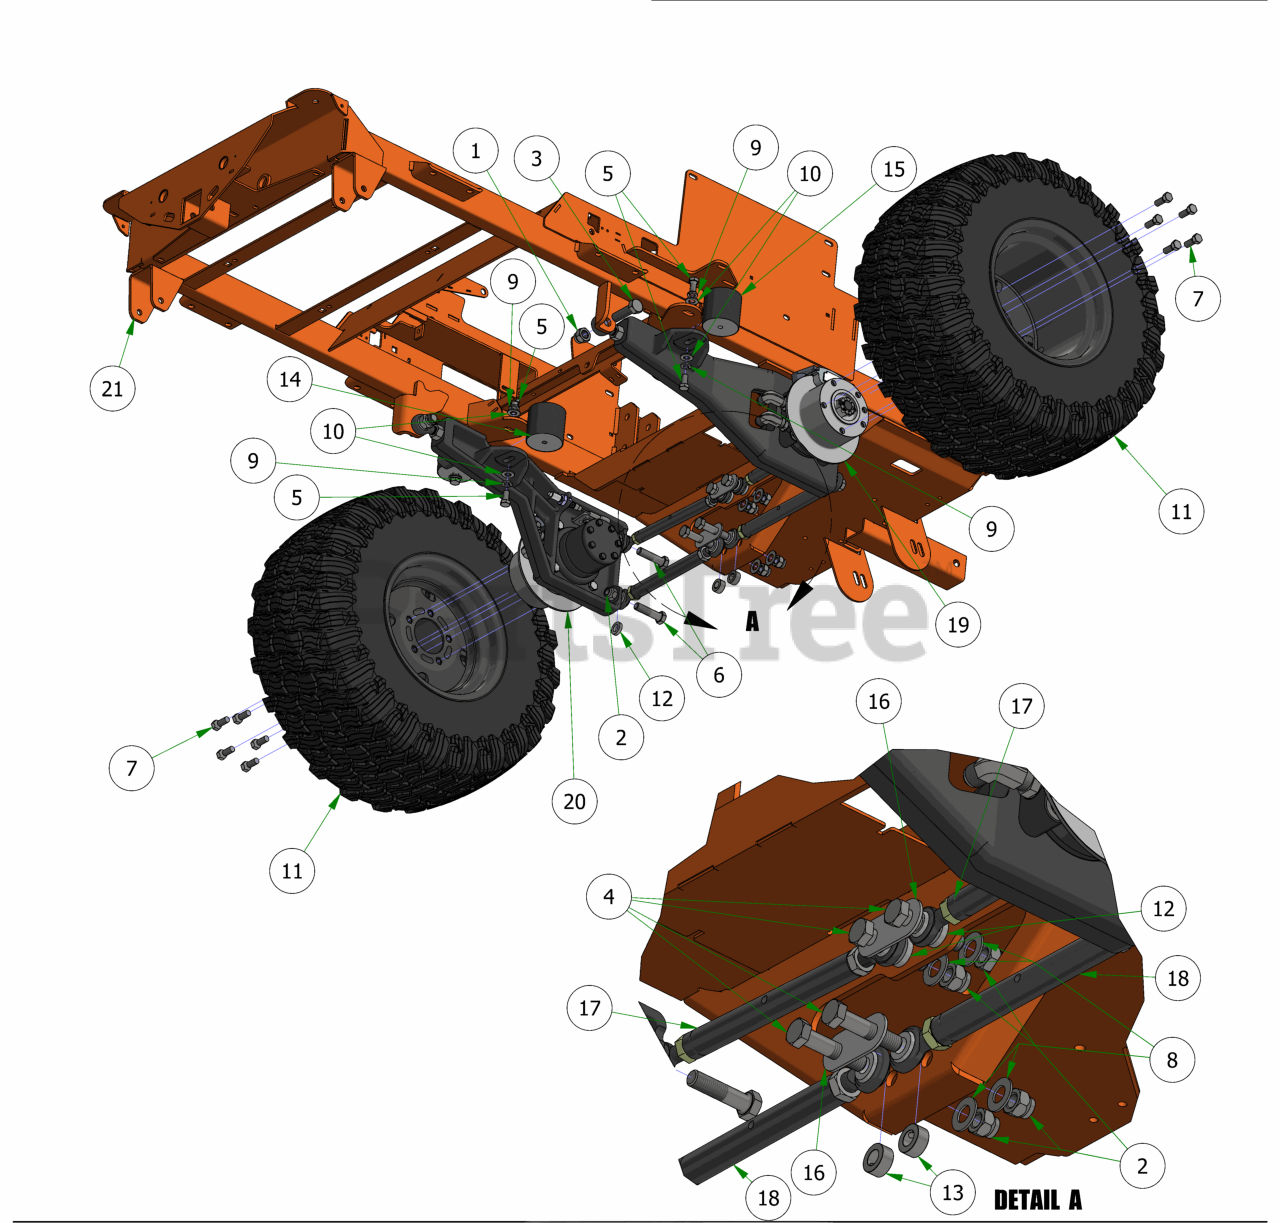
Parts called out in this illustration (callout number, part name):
1	3/4-10 NYLON INSERT LOCKNUT ZINC
2	5/8-11 NYLON INSERT LOCKNUT ZINC
3	3/4-10 X 2-1/2 HEX CAP SCREW (GR.5) ZINC
4	5/8-11 X 2-3/4 HEX CAP SCREW (GR.5) ZINC
5	1/2-13 X 1 HEX CAP SCREW (GR.5) ZINC
6	5/8-11 X 2-1/2 HEX CAP SCREW (GR.5) ZINC
7	1/2-20 x 60° Lug Bolts Zinc Grade 8
8	5/8" Flat Washer SAE Spec Grade 8
9	1/2 SPLIT LOCKWASHER (GR.8) ZINC/YELLOW
10	1/2 SAE FLAT WASHER (1-1/16" OD) GR.8 ZINC YELLOW
11	2019 Assy-26x12-12 Reaper Turf -10.5" Rim
12	Spacer 1.125OD x .625 ID x .250 Length
13	5/8 SOLID SHAFT COLLAR (W/1 SET SCREW) ZINC
14	Vibration Mount-Blue Dot
15	Vibration Mount-Green Dot
16	2019 Suspension Gusset Outlaw
17	2019 Suspension Radius Rod Assembly
18	2019 Suspension Radius Rod Assembly
19	2019 Renegade Trailing LH Arm Assy
20	2019 Renegade Trailing RH Arm Assy
21	2019 Renegade Gas Frame - Powdercoated
